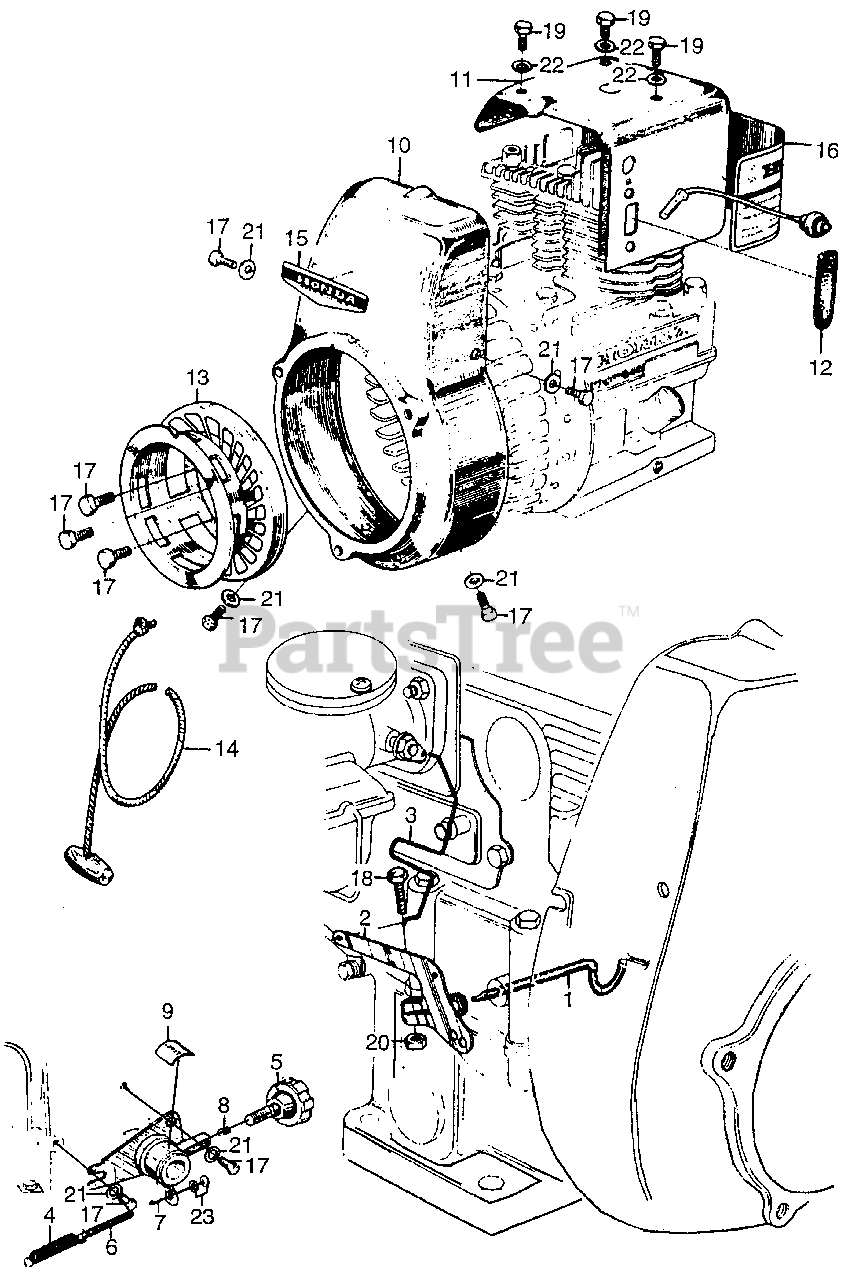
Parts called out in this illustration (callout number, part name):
1	SHAFT, GOVERNOR ARM (NOT AVAILABLE)
2	ARM, GOVERNOR
3	ROD, GOVERNOR (NOT AVAILABLE)
4	SPRING, GOVERNOR (NOT AVAILABLE)
5	SCREW, GOVERNOR ADJUSTING (NOT AVAILABLE)
6	BOLT, SPRING ADJUSTING (NOT AVAILABLE)
7	LEVER, CONTROL (NOT AVAILABLE)
8	BUSHING, CONTROL
9	PLATE, INDICATOR
10	COVER, FAN
11	COVER, SIDE *R2* (SCARLET)
12	DEFENDER, SIDE COVER
13	PULLEY, STARTER (NOT AVAILABLE)
14	ROPE, STARTER (#6X64") (NOT AVAILABLE)
16	PLATE, DESCRIPTION
17	BOLT, HEX. (6X12)
18	BOLT, HEX. (6X16)
19	BOLT, HEX. (8X16)
20	NUT, HEX. (6MM)
21	WASHER, PLAIN (6MM)
22	WASHER, PLAIN (8MM)
23	NUT, HEX. (4MM) (NOT AVAILABLE)
